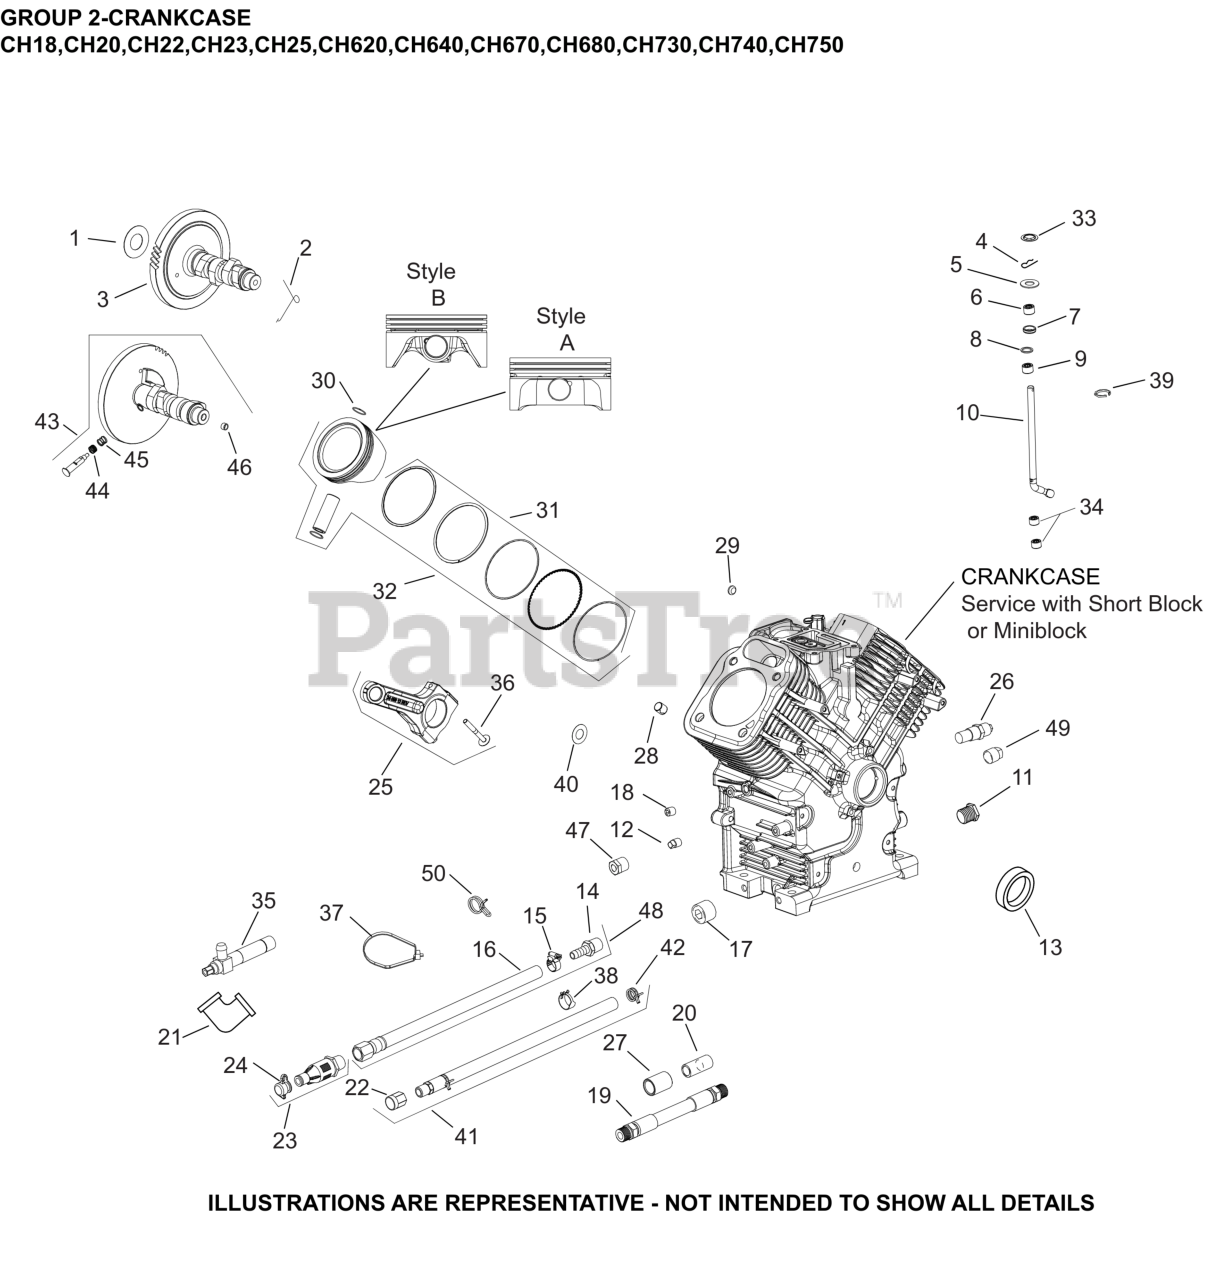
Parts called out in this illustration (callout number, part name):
3	KIT, CAMSHAFT-(#2401226S)
5	WASHER, FLAT 9 MM
7	SEAL, GOVERNOR CROSS SHAFT
8	WASHER, FLAT 11/32"
10	SHAFT, GOVERNOR CROSS
11	PLUG, HD PIPE 3/8"
13	SEAL, OIL (HELIX LIP)
23	KIT, OIL DRAIN VALVE
24	CAP, OIL DRAIN VALVE
25	ROD, ASSEMBLY CONNECTING
28	PIN, LOCATING
29	PLUG, CUP
30	RETAINER, PISTON PIN
31	RING SET(STD)STYLE B-1.2mm Tp RING THICK
31	RING SET(.08)STYLE B-1.2mm RING THICK
31	RING SET(.25)STYLE B-1.2mm Tp RING THICK
31	RING SET(.50)STYLE B-1.2mm Tp RING THICK
32	KIT, PISTON 725CC (STD) STYLE B
32	KIT, PISTON 725CC (.08) STYLE B
32	KIT, PISTON 725CC (.25) STYLE B
32	KIT, PISTON 725CC (.50) STYLE B
33	RETAINER, RING
36	KIT, ROD BOLTS-(#25086677S)
